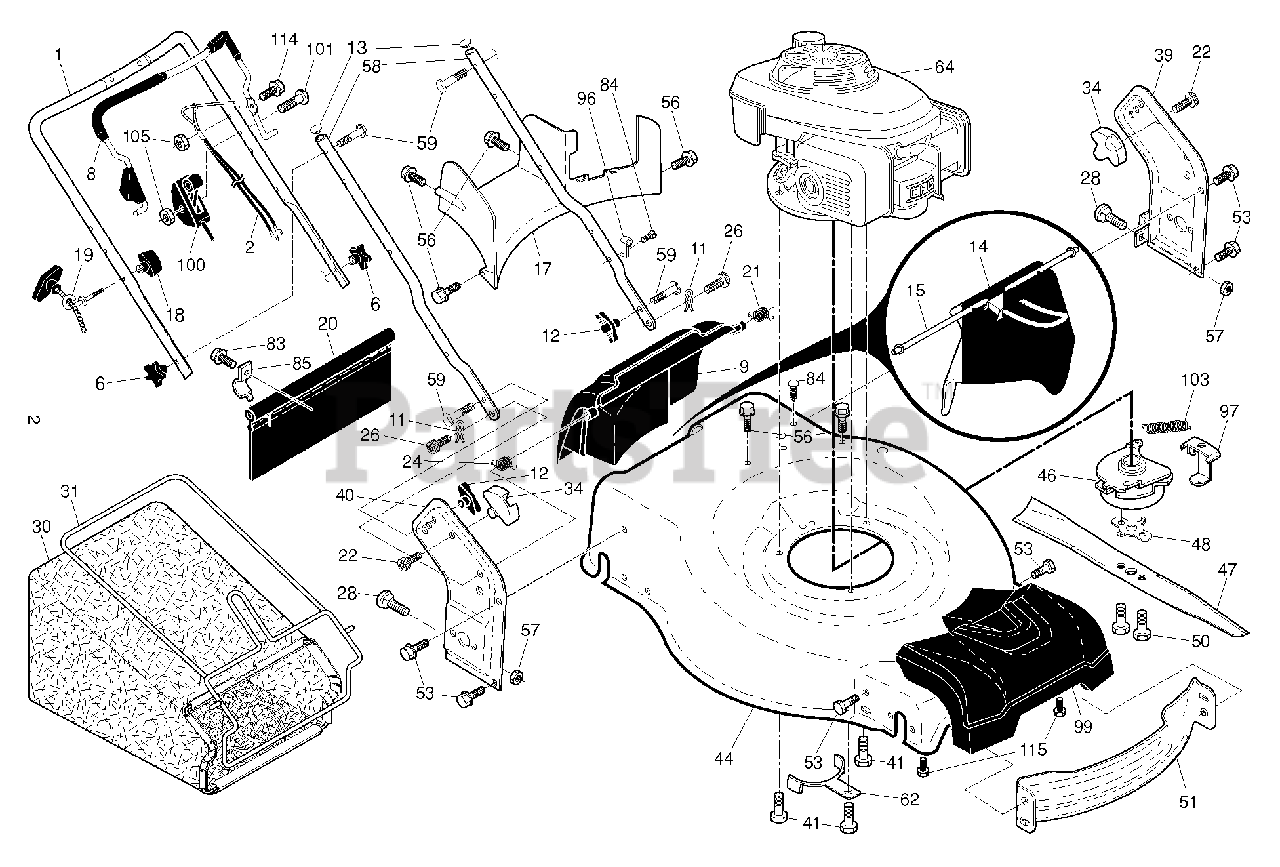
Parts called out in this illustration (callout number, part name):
1	HANDLE.UP.3POS.BS.AW2.GREY
2	CABLE.BBC.HONDA.NO.RDI.22+
6	KNOB.HANDLE.PLASTIC.STAR.BLACK
8	LEVER.ASM.BBC.HONDA.ERGO.OM.O
9	DOOR.REAR.ASM.22+.HUSQ.FG/RGD
11	COTTER.HAIRPIN.DOOR/HANDLE.PIV
12	KNOB, DEFLECTOR
13	PLUG.PLASTIC.7/8".14-20.GAUGE
14	DEFLECTOR.CHUTE.22+REAR
15	HANDLE DEFLECTOR.22+REAR
17	BAFFLE.REAR.22+RGD.AWD.PLASTIC
18	T-KNOB.NEW ROPE GUIDE
19	GUIDE.ROPE.BLK.ZINC.CHROM
20	SKIRT.REAR.22PLUS.RGD.LW(2 2MC
21	SPRING.LH.BLACK
22	SCREW.PAN.HEAD.#10
24	SPRING.RH.GRAY
26	SCREW,DOOR/HANDLE.PIVOT
28	BOLT
30	GBAG.BA85028ER.GRY/ORG
31	FRAME.GBAG.22+.BLK
34	BRACKET.GRASSBAG.ATTACHING.BLK
39	BRACKET.ASM.HANDLE.LT.22+.GREY
40	BRACKET.ASM.HANDLE.RT.22+.GREY
41	BOLT 3/8-16X1-1/8
44	HOUSING.22+R.RG.HD.WO.LT/ST.OR
47	BLADE.3N1.22+W/HONDA.BBC.PREM
48	SPACER.BLADE.HONDA.BBC
50	BOLT.BLADE
51	BAFFLE.FRONT.22.PLUS
53	BOLT.5/16HEX.WHS.HD
56	SCREW.HX.13X.750
57	NUT.FLANGE.5/16
58	HANDLE.LOWER.22+.BT.GRAY
59	BOLT, HANDLE 5/16-18X1.75
62	BRACKET.KEEPER.BELT
83	TAPPING SCREW
84	FASTENER.PUSH.O.250X0.783
85	BRACKET.SKIRT.22+.BZP
96	CLIP.CABLE.BLK
97	BRACKET.ASM.BBC.MOUNTING.BZP
99	COVER.ASM.FRONT.HUSQ.22+RGD
100	CONTROL.THROTTLE.HOND.BBC.58.5
103	SPRING.BBC
105	NUT
115	SCREW.HI-LO. 5/16 X 1.00
